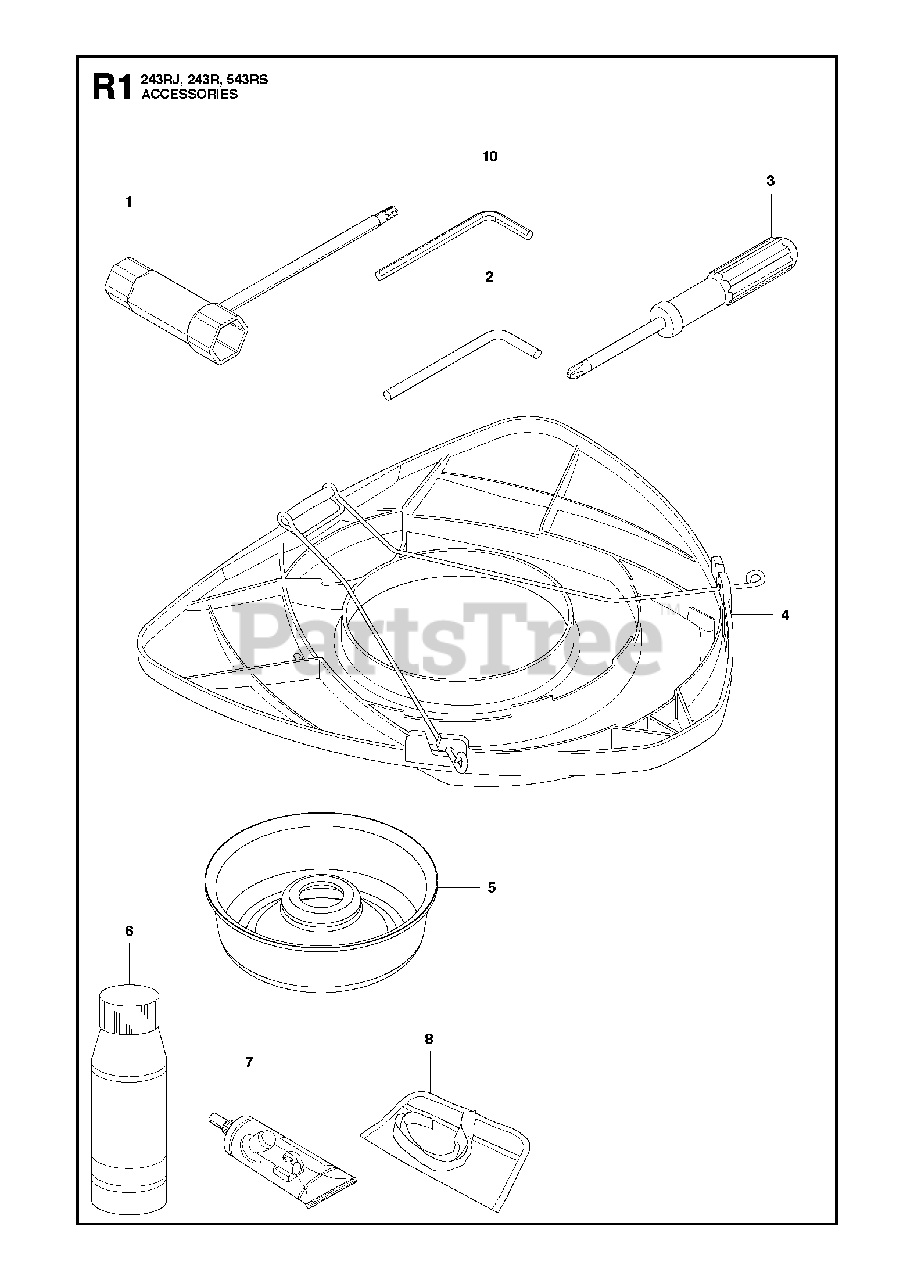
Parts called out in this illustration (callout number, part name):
4	TRANSPORT GUARD
5	Support Cup
6	Air Filter Oil, HVA 1L Bottle
7	BEVEL GEAR GREASE
9	STRAP
10	WRENCH
